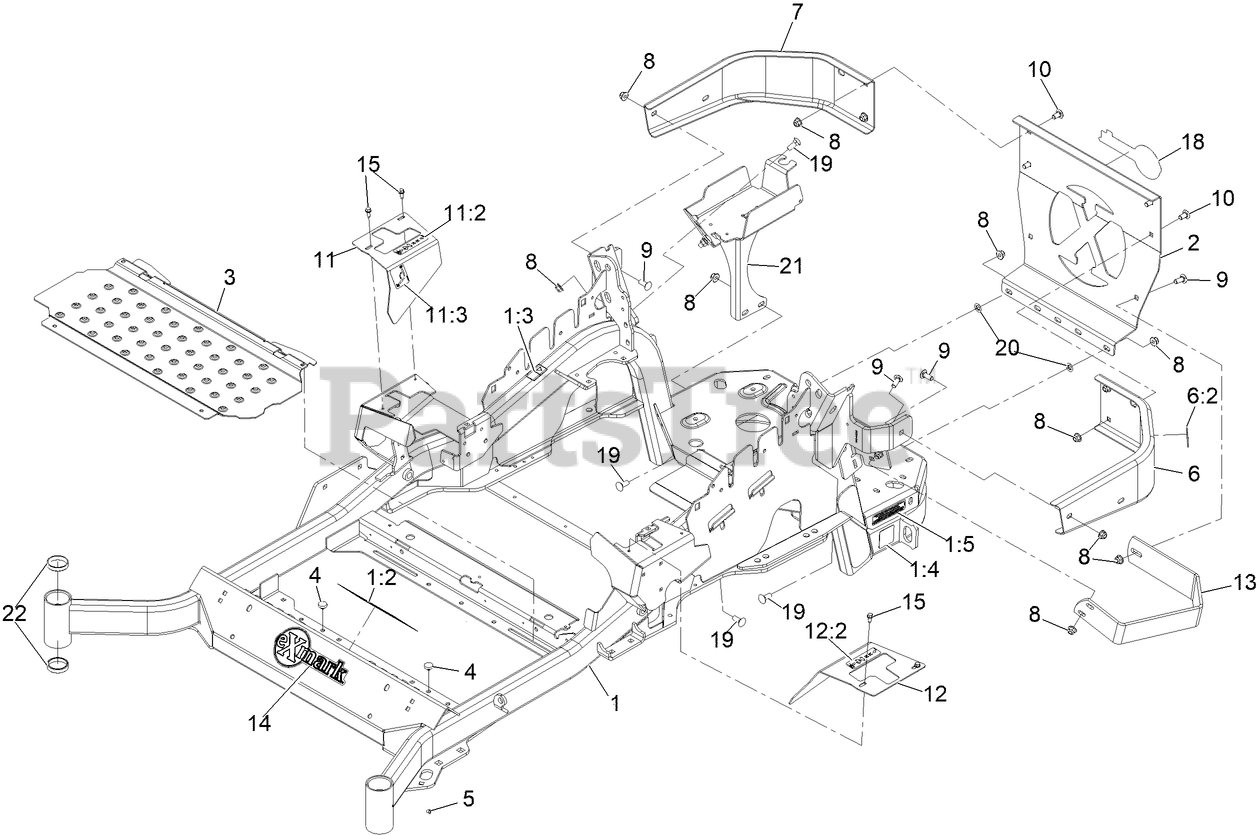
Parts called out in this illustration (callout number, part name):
1	Mainframe ASM-60 W/Decals
1:2	DECAL-ARRESTOR, SPARK
1:3	DECAL-WARNING
1:4	DECAL-HAZARD, PINCHED FINGER
1:5	DECAL-DANGER
2	PLATE,REAR GUARD
6	LH BUMPER ASM
6:2	DECAL-WARNING
7	BUMPER-RH
8	NUT-HF, NI
9	SCREW-CARR
10	SCREW-CARR
11	RH MOTION CONTROL COVER ASM
11:2	DECAL-CONTROL, MOTION
11:3	DECAL-PARK BRAKE, CE
12	LH MOTION CONTROL COVER ASM
12:2	DECAL-CONTROL, MOTION
13	GUARD-MUFFLER
14	DECAL-EXMARK
15	SCREW-HWH
18	DECAL, EXMARK LOGO
19	BOLT-CARR
20	NUT-PUSH
21	Weld-Battery Mount
22	CUP-BEARING
